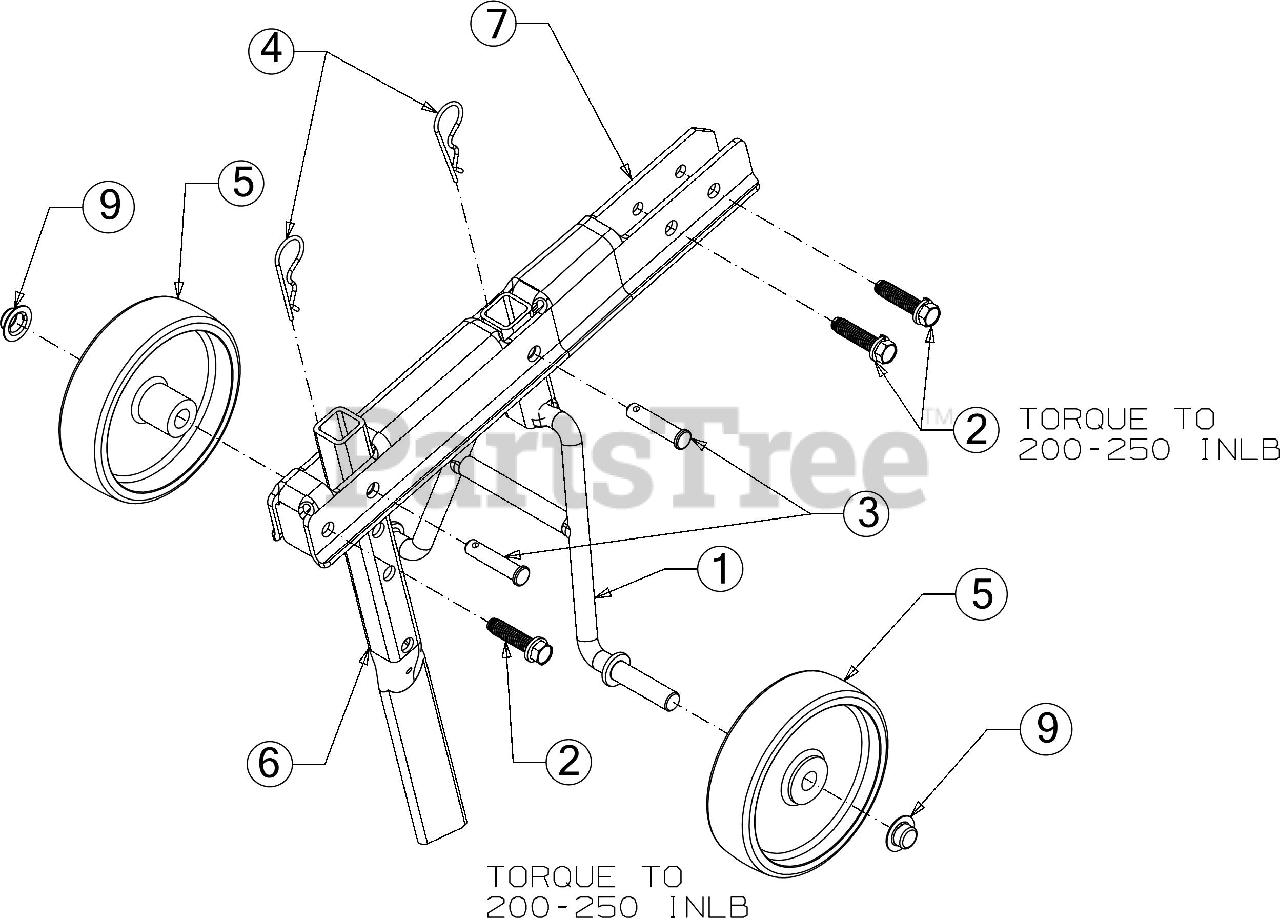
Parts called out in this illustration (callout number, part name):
1	WHEEL ROD ASSEMBLY (REAR)
2	SCREW 3/8-16 X 1.500
3	CLEVIS PIN .375 X .1.75
4	INTERNAL COTTER PIN
5	PLASTIC WHEEL 5X1.38
6	DEPTH STAKE TUBE
7	WHEEL BRACKET
9	PUSH CAP
